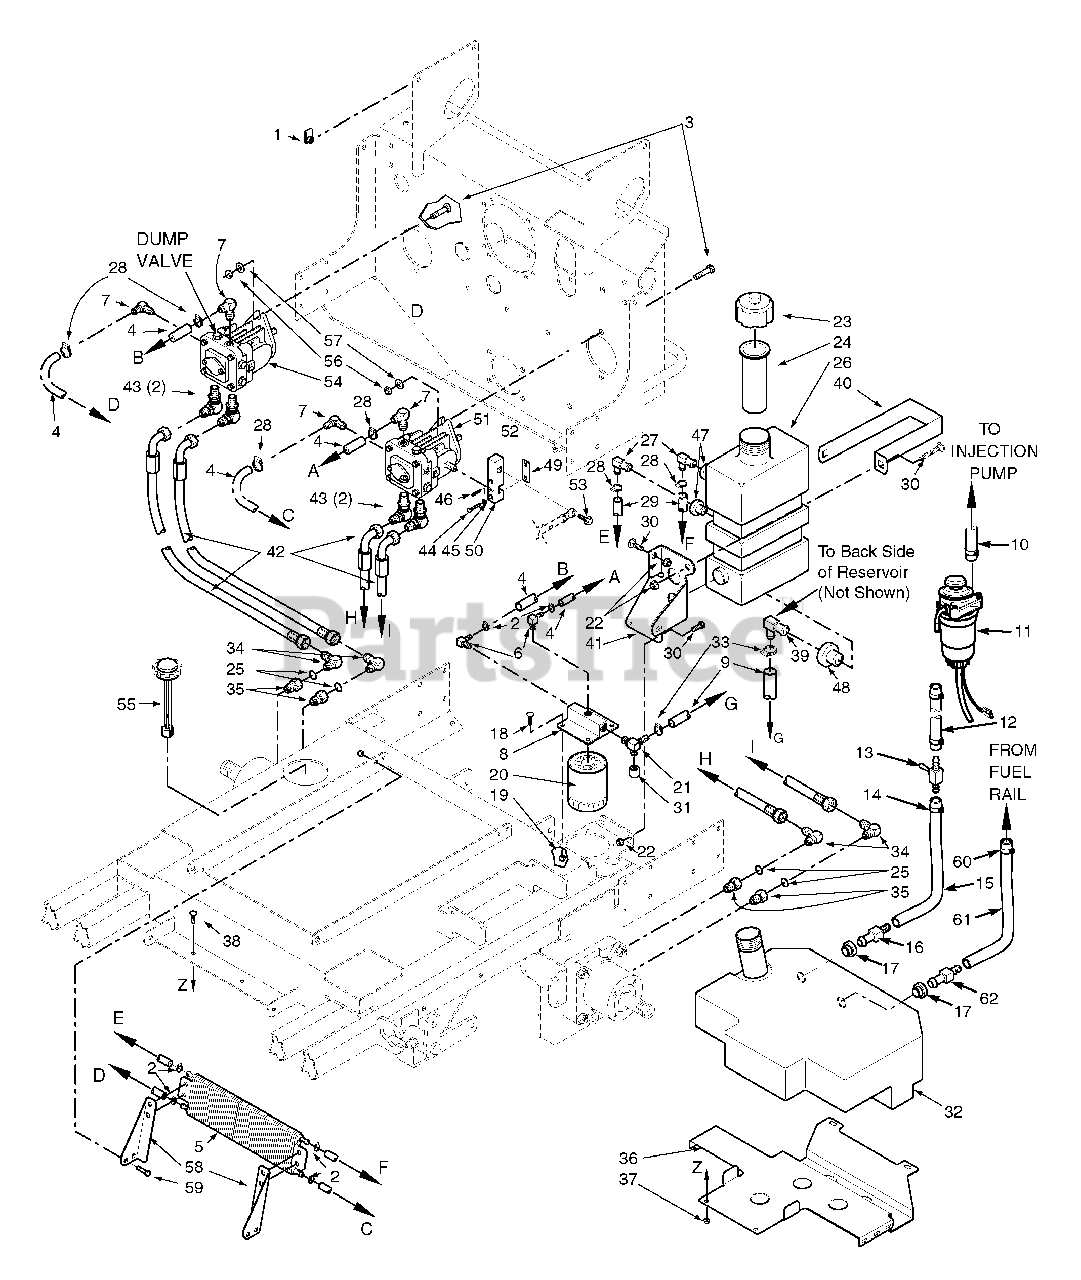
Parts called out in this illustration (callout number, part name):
1	U-Nut 1/4-20
2	Hose Clamp, 0.69 dia.
3	Bolt, Hex Head 1/4-20 x 2.0"
4	Hose, 3/8" ID Pushlock - (order by inch)
5	Cooler, Oil
6	Elbow, 90 Degree - 9/16 O-ring x 3/8 Hose
7	Elbow, 90 Degree - 3/4 O-ring x 3/8 Hose
8	Oil Filter Base
9	Hose Assembly, 1/2" ID (Tank to Filter Base)
10	Fuel Hose to Carb., 1/4" ID (order by inch)
11	Fuel Filter (Purchase from Briggs & Stratton)
12	Fuel Hose, 1/4" ID. (order by inch)
13	Valve, Shutoff
14	Clamp, Fuel Hose 5/16 ID
15	Fuel Hose, 5/16" ID. (order by inch)
16	Hose Fitting
17	Bushing
18	Bolt, Hex Head 5/16-18 x1.0" Zinc
19	Nut, Serrated Flange 5/16-18
20	Oil Filter
21	Tee, 3/4 O-ring x JIC x 1/2" Hose
22	Nut, Hex Elastic Stop 1/4-20
23	Cap, Hydraulic Tank
24	Insert, Filler Neck
25	O-Ring
26	Oil Reservoir Assembly
27	Elbow, 90 Degree, 9/16-18 JIC x 9/16 O-Ring
28	Hose Clamp, 0.69 dia.
29	Hose, 3/8" ID, Pushlock (order by inch)
30	Screw, Phillips Head, 1/4-20
32	Fuel Tank Assembly
33	Clamp, Hose
34	Elbow, 90 Degree, 7/8-14 THD
35	Bushing, 7/8-14 JIC x 3/4-16 O-Ring
36	Support Bracket, Fuel Tank
37	Nut, 5/16-18 Serrated Flange
38	Bolt, Carraige 1/4-20 x 3/4"
39	Elbow, 90 Degree
40	Strap, Hydraulic Tank
41	Support Bracket, Hydraulic Tank
42	Hose Assembly, Pump
43	Elbow, 90 Degree 7/8-14 Thread
44	Bolt, Hex Head, 1/4-20 x 1-14"
45	Lockwasher, 1/4" Spring
46	Roll Pin, Spring 3/16 x 3/4"
47	Bushing, .56 Dia.
48	Bushing, .78 Dia.
49	Clamp Plate, Pump Control
50	Block, Pump Control
51	Pump, Left Hand, BDP-21L-305
52	Nut, Hex, Elastic Stop 3/8-16
53	Bolt, Hex Head, 3/8-16 x 1-1/4
54	Pump, Right Hand, BDP-21L-403
55	Cap, Fuel Tank W/Gauge
56	Nut, Hex Elastic Stop 3/8-16
57	Flatwasher, 3/8" (.391 x .938 x .105) Grade 8
58	Mounting Bracket - LH, Oil Cooler
59	Bolt, Hex Head 5/16-18 x 3/4"
60	Clamp, 3/16 Hose
61	Hose, 3/16" I.D. (order by inch)
62	Hose Fitting, Straight DAPCO
